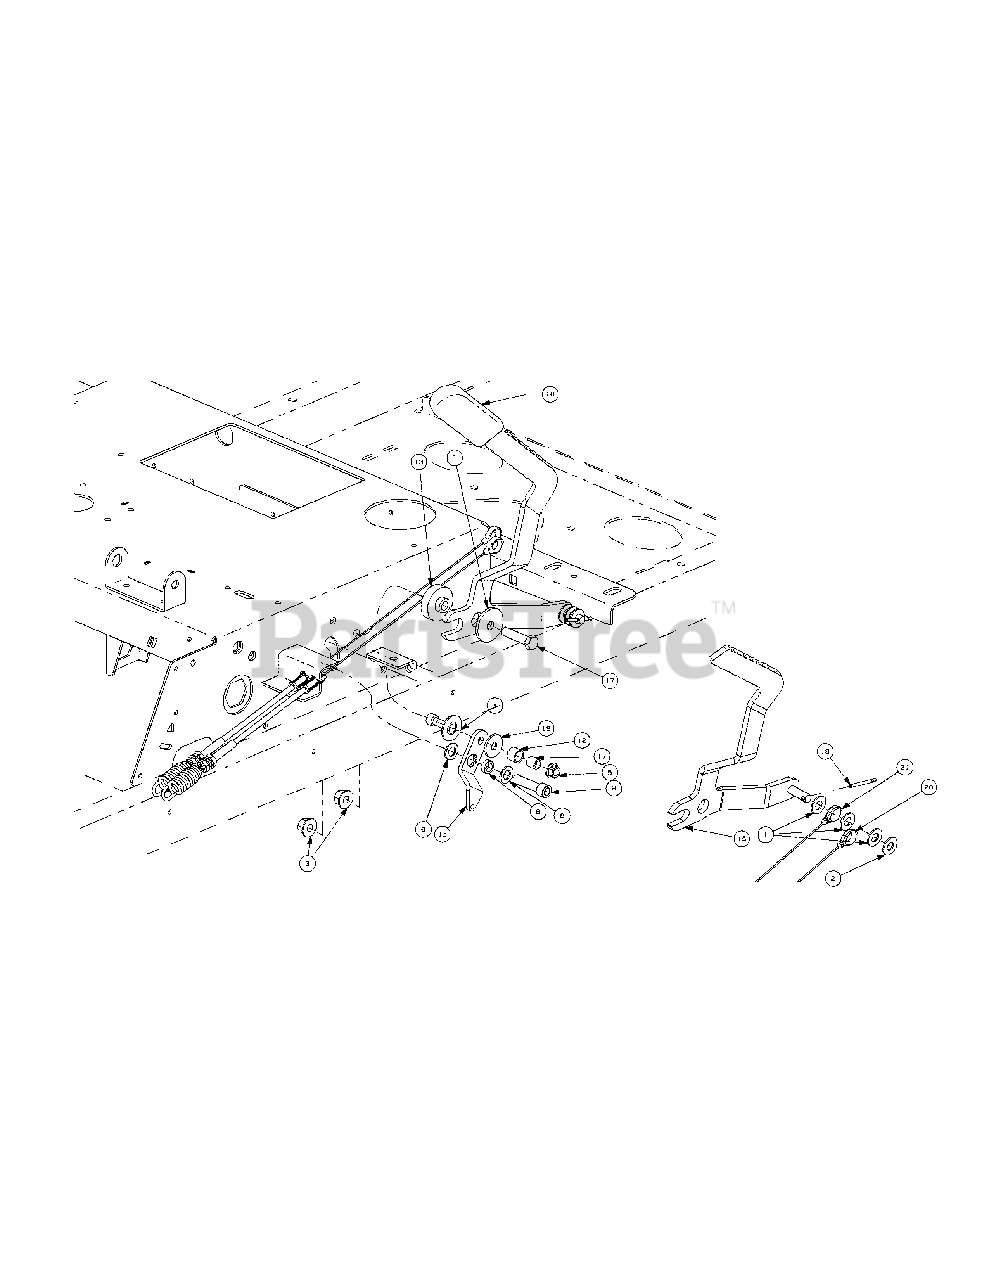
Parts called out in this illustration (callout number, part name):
1	Washer, .406 x .812 x .062
2	Hex Head Cap Screw, 5/16-18 x 1.00
3	Hex Nut, 3/8-16 Flange Lock
4	Slide Washer
5	Nut, 5/16-18, Flange Lock
6	Washer, .375 x .738 x .063
7	Flat Washer, .390 x 1.5 x .134
8	Spacer, .380 x .563 x .196
9	Sockethead Capscrew, 3/8-16 x 1.50
10	Parking Brake Grip
11	Spacer, .322 ID x .438 OD x .44
12	Spacer, .442 ID x .563 OD x .405
13	Step Hub, .379 x 1.5 x .257/.400
14	Sockethead Capscrew, 5/16-18 x 1.00
15	Lockout Lever Plate
16	Brake Handle
17	Hex Head Cap Screw, 3/8-16 x 1.50
18	Cotter Pin, .125 OD X .75
19	Washer, .345 x 1.00 x .100
20	Left Hand Brake Cable
21	Right Hand Brake Cable
